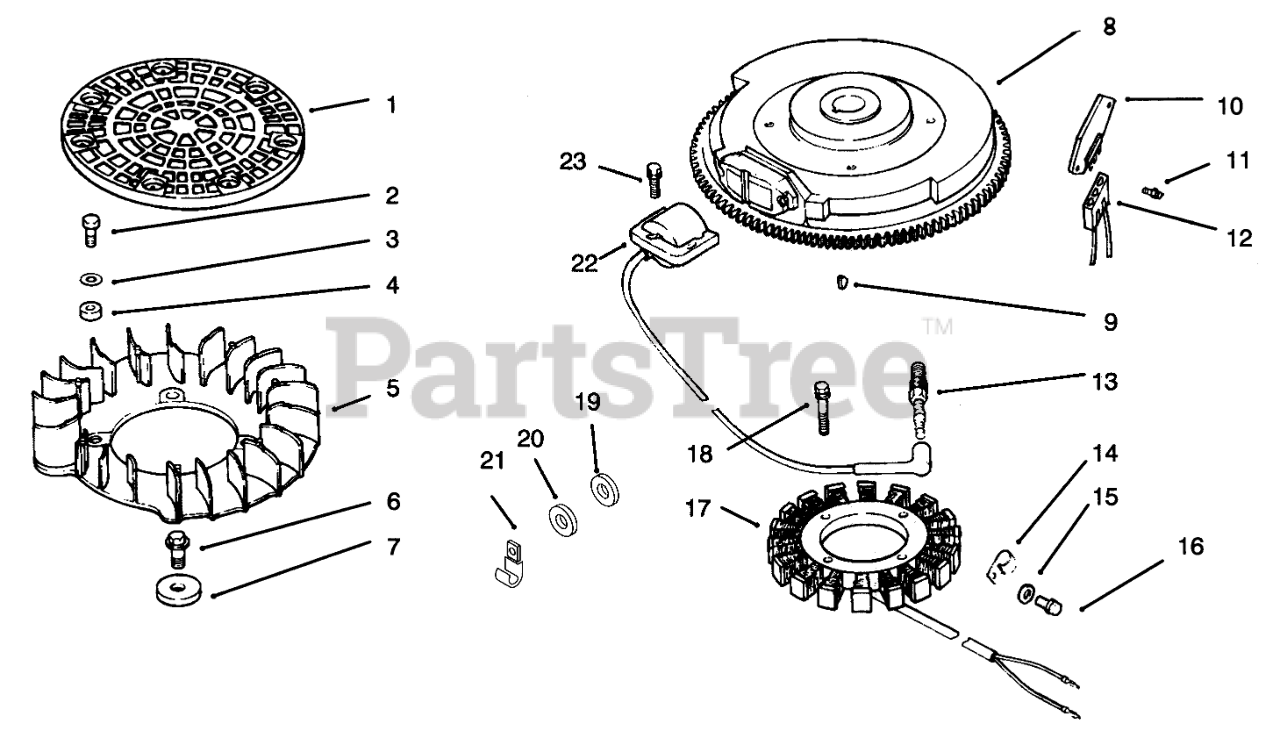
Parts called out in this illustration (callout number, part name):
1	Screen-Grass (Only On: 72103)
2	Screw M4x0.7x24 (Only On: 72103)
3	Washer-Flat (Only On: 72103)
4	Spacer-Fan (Only On: 72103)
5	Fan (Only On: 72103)
6	Screw M6x1.0x16 (Only On: 72103)
7	Spacer-Fan (Only On: 72103)
8	Flywheel ASM (Only On: 72103)
9	Key (Only On: 72103)
10	Rectifier-Regulator (Only On: 72103)
11	Screw-Phillips (Only On: 72103)
12	Connector-Regulator (Only On: 72103)
13	Spark Plug (Only On: 72103)
14	Clip-Stator Harness (Only On: 72103)
15	Washer-Flywheel Screw (Only On: 72103)
16	Screw-Flywheel Mounting (Only On: 72103)
17	Stator-15 Amp (Only On: 72103)
18	Screw M5x0.8x25 (Only On: 72103)
19	Washer-Flat (Only On: 72103)
20	Washer-Flat (Only On: 72103)
21	Clip-Cable (Only On: 72103)
22	Module-Ignition (Only On: 72103)
23	Screw M5x0.8x20 (Only On: 72103)
